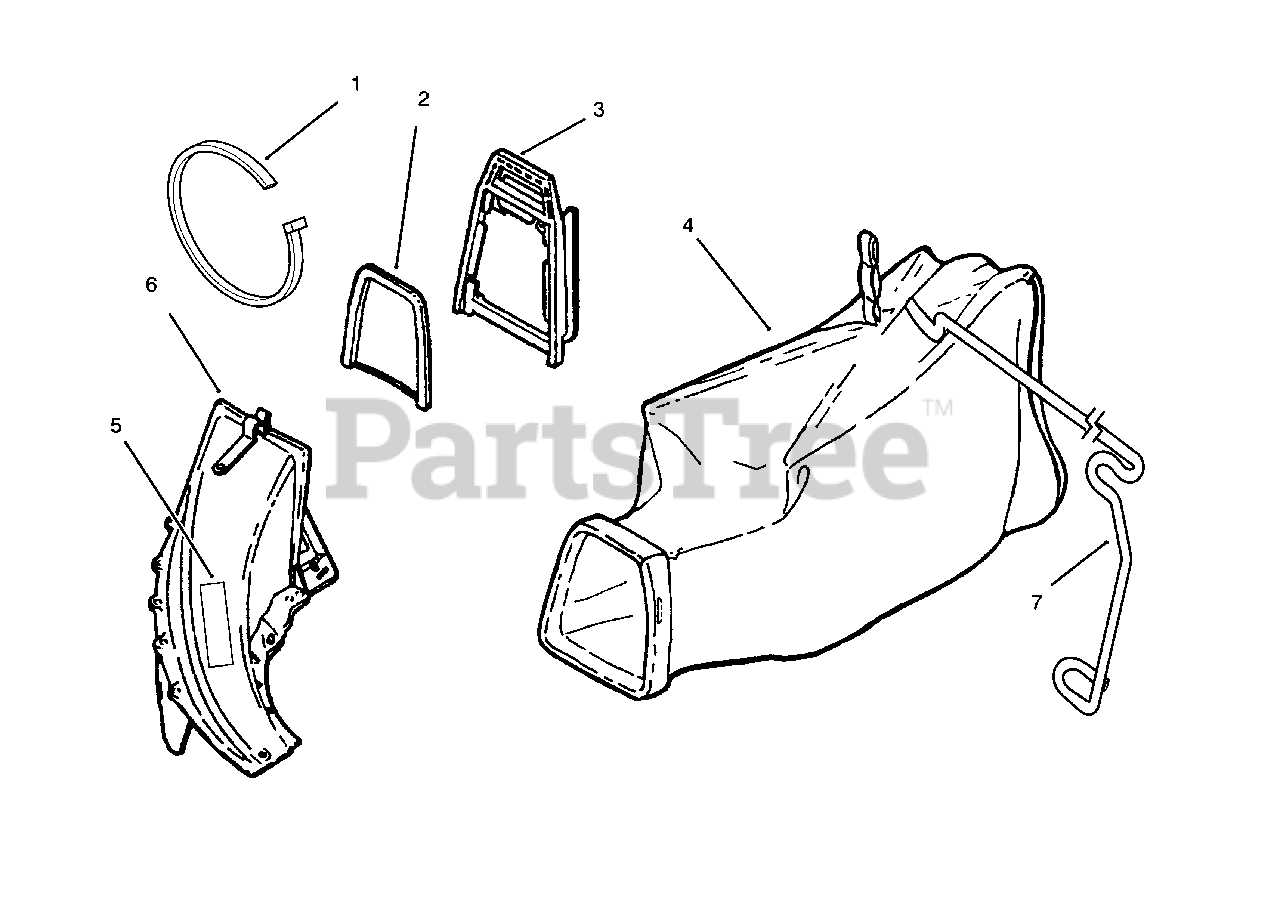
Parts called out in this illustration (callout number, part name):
1	Strap-Tie
2	Brace-Chute
3	Adaptor-Chute
4	Bag-Leaf (Incl Ref.# 1 & 3)
5	Decal-Danger
6	Chute Assembly
7	Rod-Grass Bag
